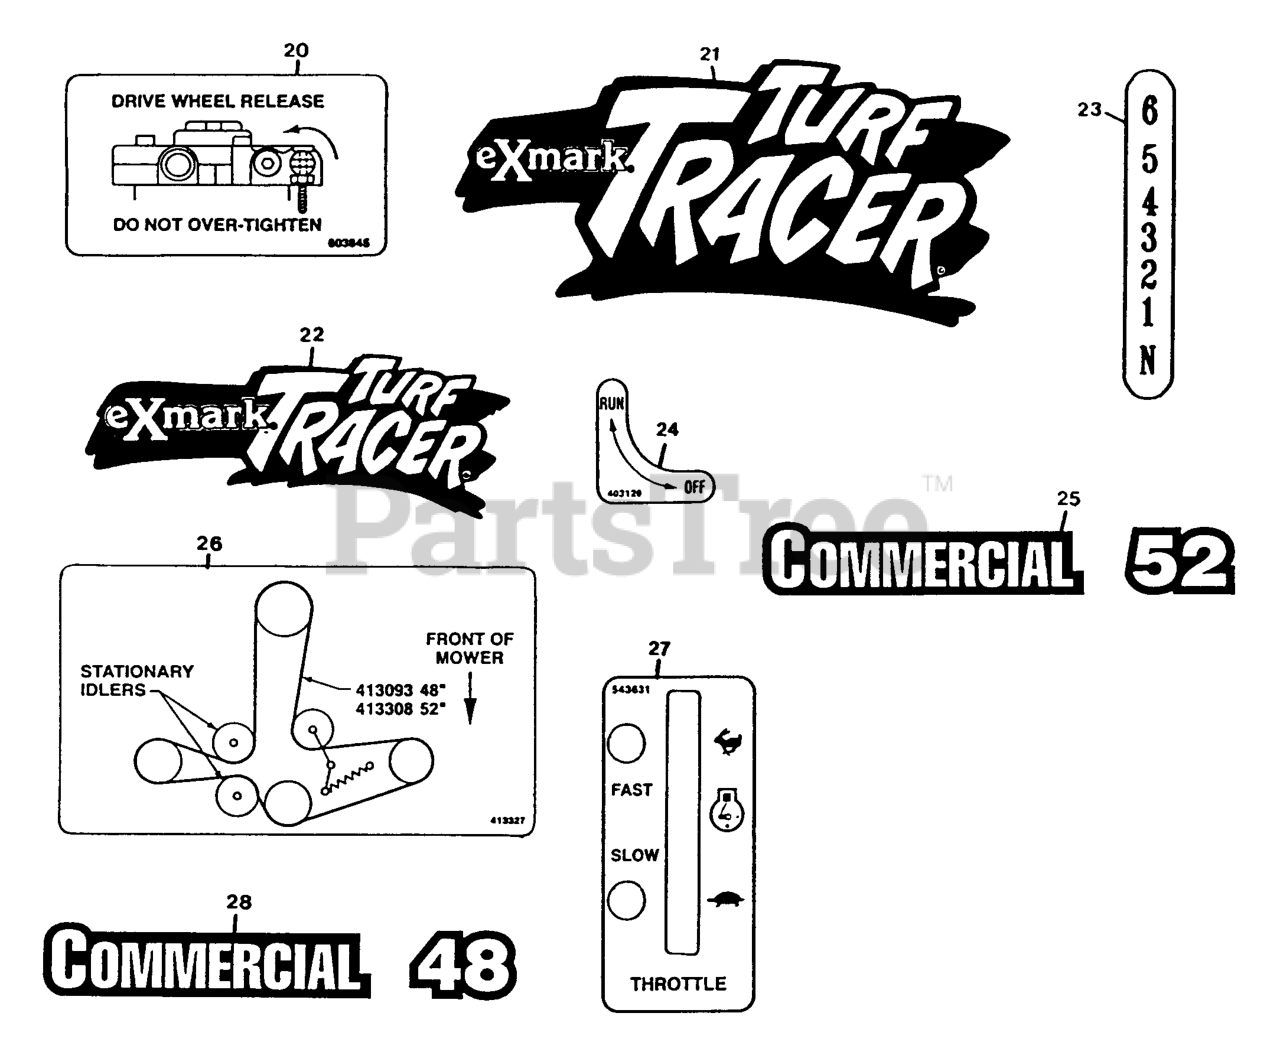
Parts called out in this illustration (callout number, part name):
20	DECAL,DRIVE RELEASE
23	DECAL - SHIFTER
25	DECAL,COMMERCIAL 52
26	DECAL,BELT ROUTING
28	DECAL,COMMERCIAL 48
